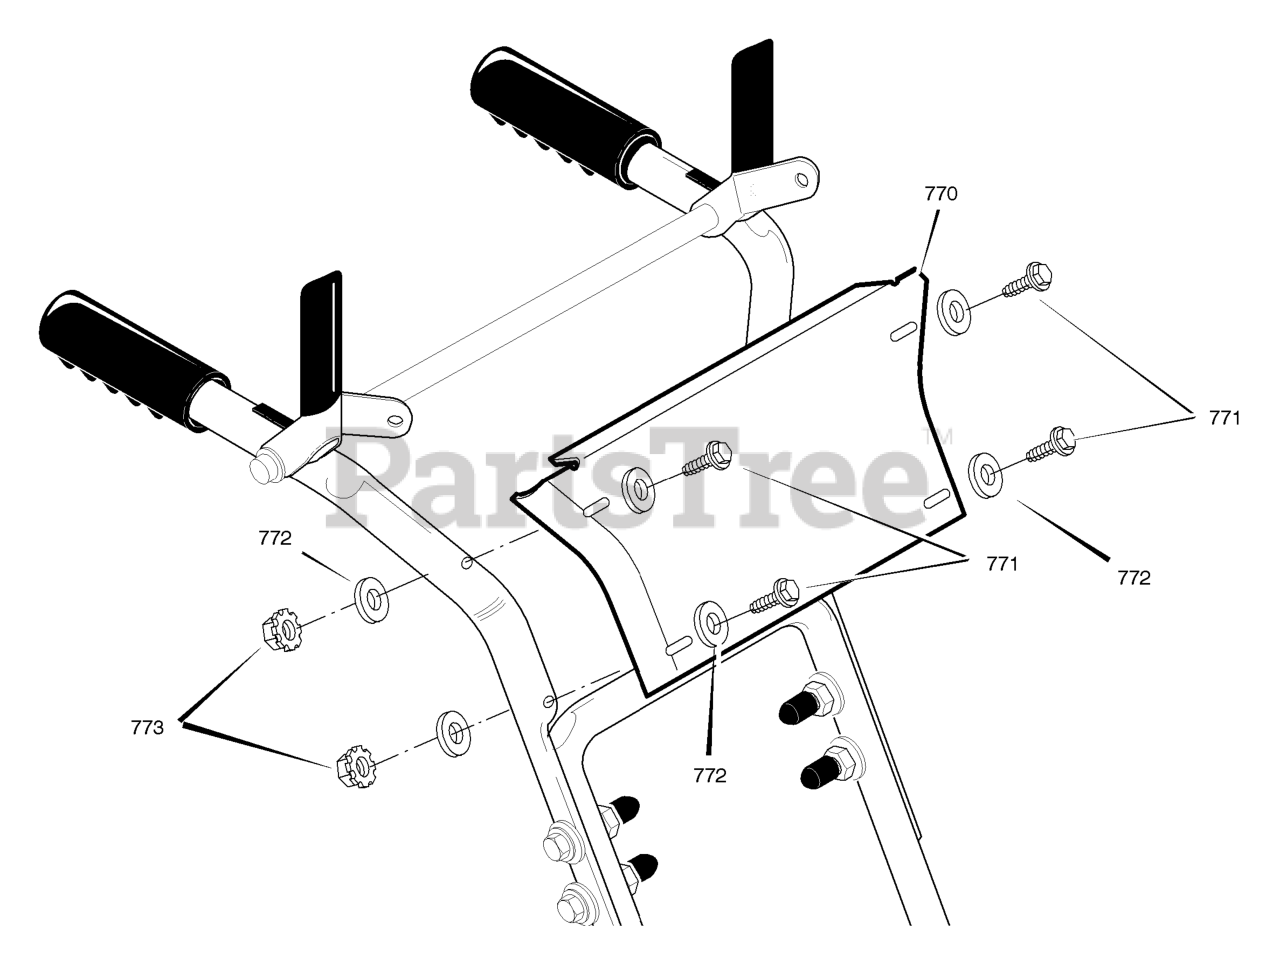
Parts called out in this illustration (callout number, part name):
770	CONTROL PANEL
771	BOLT 1/4-20X1.5
772	WASHER
773	NUT
